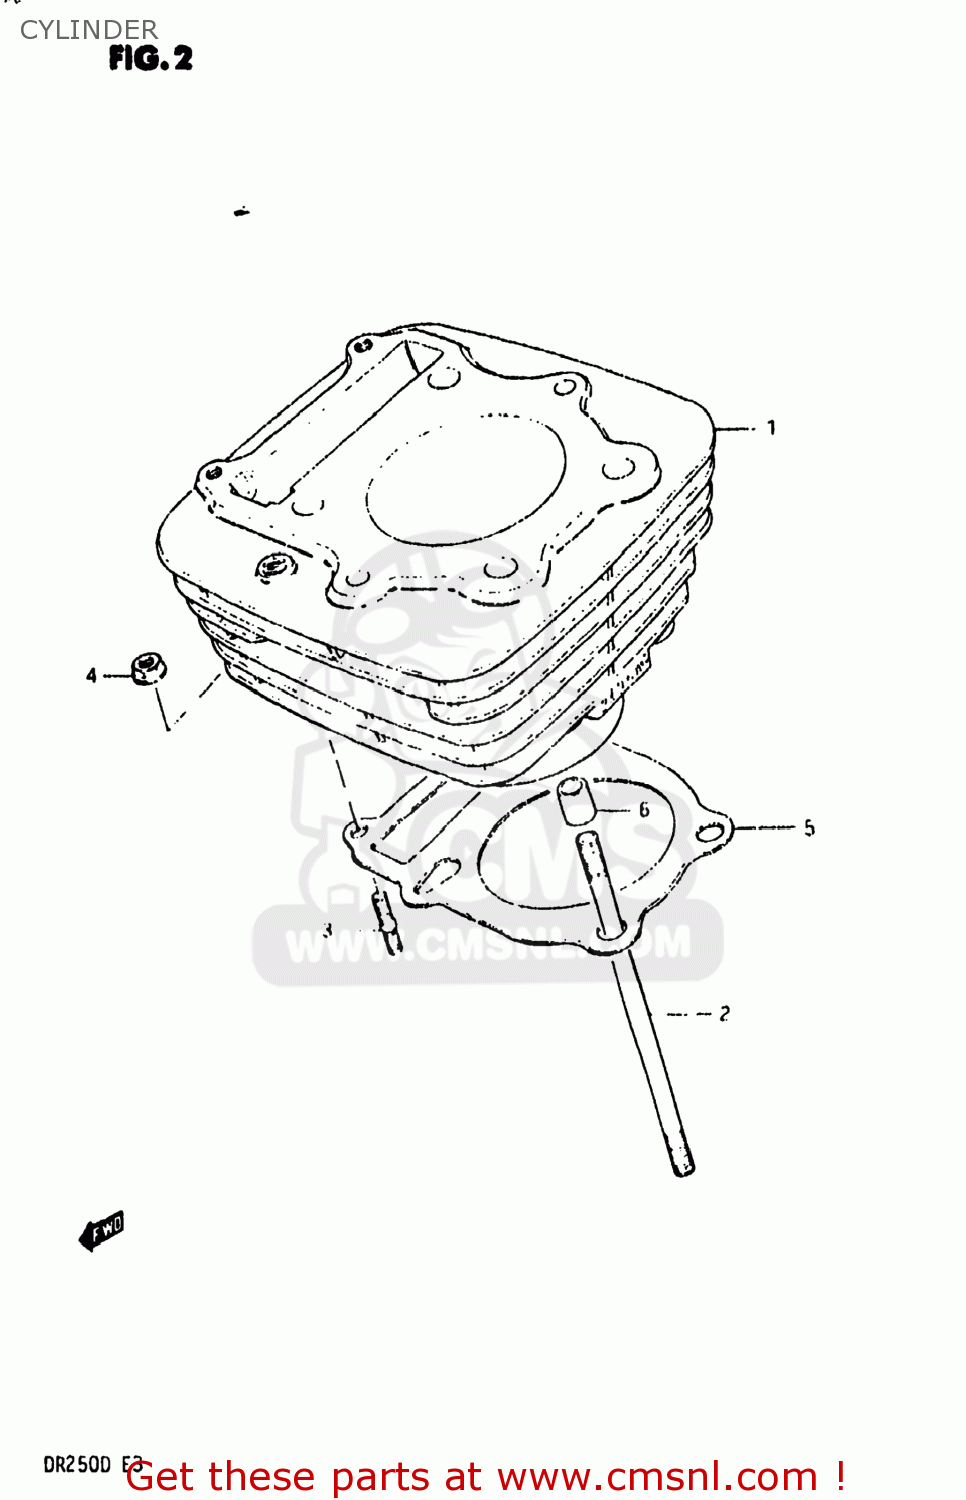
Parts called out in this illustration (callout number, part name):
1	CYLINDER
2	BOLT,STUD
3	STUD 6X25
4	NUT
5	GASKET,CYLINDER (MCA)
6	PIN
